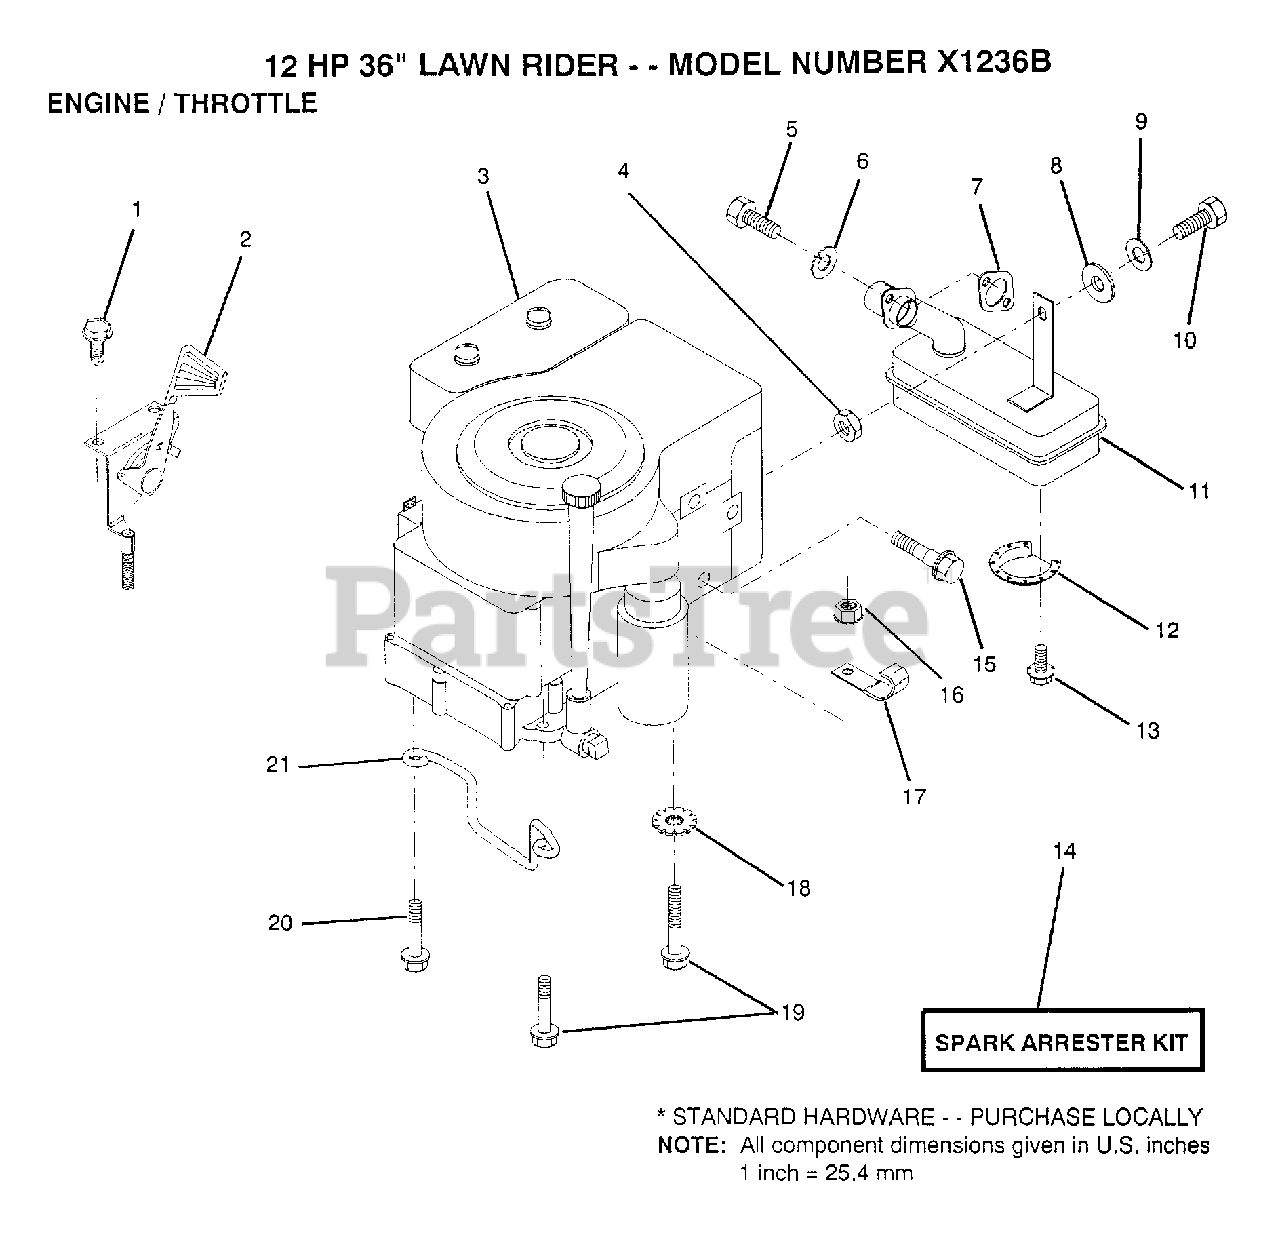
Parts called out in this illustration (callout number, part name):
1	SCREW
3	ENGINE BRIGGS AND STRATTON
4	NUT.HEX.5/16-18
5	SCREW
6	LOCKWASHER
9	LOCKWASHER
10	BOLT
11	MUFFLER
12	DEFLECTOR.222573
15	BOLT T
16	NUT
17	CLIP T
18	LOCKWASHER
19	SCREW LT
20	SCREW LT
21	"KEEPER,DR BELT GR"
